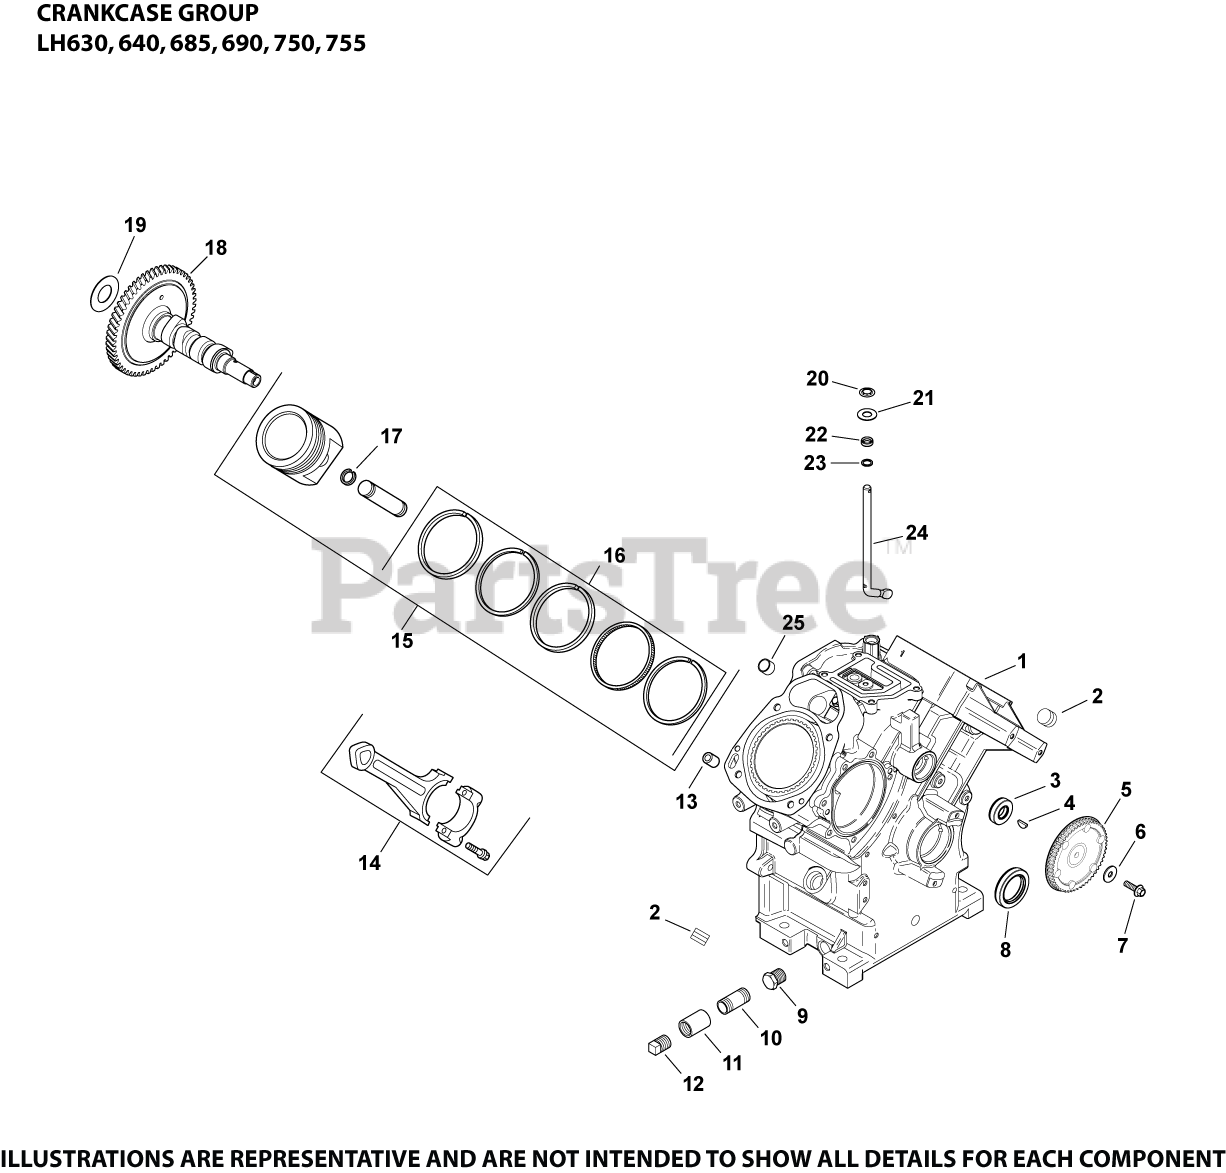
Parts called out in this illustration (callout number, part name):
1	CRANKCASE
2	PLUG, PIPE CTSK 3/8"
3	SEAL, CAMSHAFT
4	KEY, 3/32" X 3/8"
5	SPROCKET, CAMSHAFT
6	WASHER, FLAT 1/4"
7	SCREW, FLG M6x1.0x20
8	SEAL, OIL (HELIX LIP)
10	NIPPLE, PIPE
11	COUPLING, PIPE
12	PLUG, SQ HD PIPE 3/8"
13	PIN, LOCATING
14	ROD, ASSY CONNECTING (STD)-(#2406730S)
14	ROD ASSY, CONNECTING U/S (.010”) (.25 mm) -USE 24 067 31-S
15	PISTON W.RINGS, STYLE A STD
15	PISTON W/RINGS (STYLE A)(.08) - RING SET 24 108 19-S USE 24 874 55-S
15	PISTON W/RINGS (STYLE A)(.25) - RING SET 24 108 20-S - USE 24 874 56-S
15	PISTON W/RINGS (STYLE A)(.50) - RING SET 24 108 21-S
16	RING SET (STYLE A)(STD) 1.5MM TOP RING THICKNESS USE PISTON ASSY PER SPEC - Discontinued
16	RING SET (STYLE A) (.08) 1.5MM TOP RING THICKNESS -DISCONTINUED
16	RING SET (STYLE A)(.25)1.5MM TOP RING THICKNESS - USE 24 874 44-S
16	RING SET (STYLE A)(.50)1.5MM TOP RING THICKNESS
17	RETAINER, PISTON PIN
18	KIT, CAMSHAFT
19	SHIM, CAMSHAFT (WHITE .028")
19	SHIM, CAMSHAFT (BLUE .03")
19	SHIM, CAMSHAFT (RED .032")
19	SHIM, CAMSHAFT (YELLOW .034")
19	SHIM, CAMSHAFT (GREEN .036")
19	SHIM, CAMSHAFT (GRAY .038")
19	SHIM, CAMSHAFT (BLACK .04")
20	RETAINER, RING
21	WASHER, FLAT 9 MM
22	SEAL, GOVERNOR CROSS SHAFT
23	WASHER, FLAT 11/32"
24	SHAFT, GOVERNOR CROSS
25	PLUG, CUP
